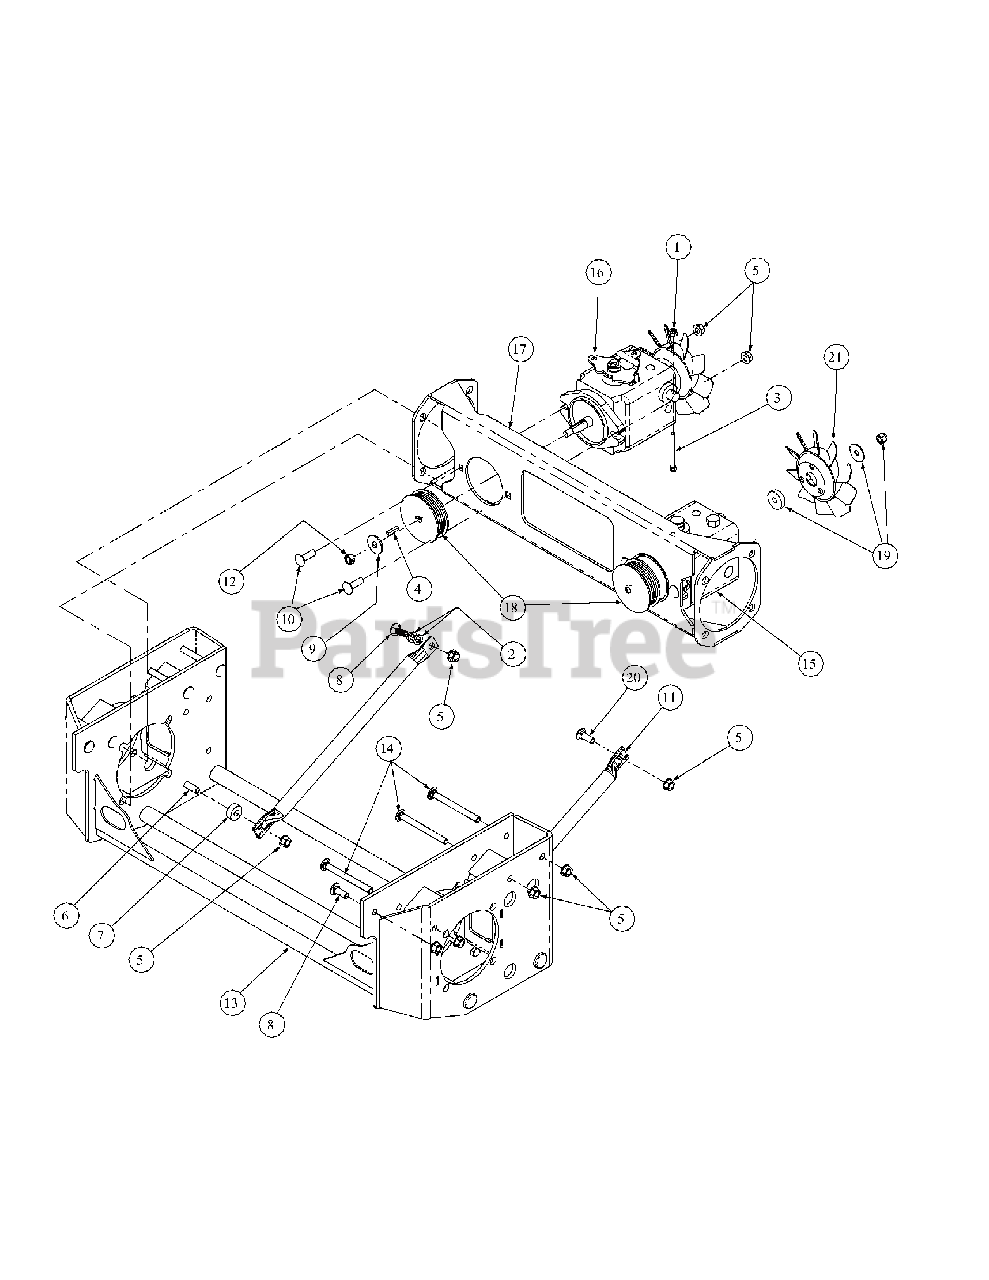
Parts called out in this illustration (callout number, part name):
1	Lock Nut, Nylon Insert, 1/4-20
2	Washer lock 3/8 zinc
3	Hex Cap Screw, 1/4-20 x 2.00
4	Key, 3/16" x 7/8"
5	Flange Lock Hex Nut, 3/8-16
6	Hex Cap Screw, 2/8 -16 x 1.25
7	Spacer, .406 ID x 1.00 OD x .38
8	Carriage Bolt, 3/8-16 x 1
9	Flat Washer, 3/8
10	Carriage Screw, 3/8-16 x 1.25
12	Hex Nut, 3/8-24
13	Hydro Motor Frame Assembly
14	Carriage Bolt, 3/8-16 x 4.00
15	Hydro Pump, RH
16	Hydro Pump, LH
17	Hydro Pump Mounting Weldment
18	Hydro Pulley Pump
19	Kit, Fan Hardware w/o Fan
20	Carriage Bolt, 3/8-16 x .75
21	Fan
